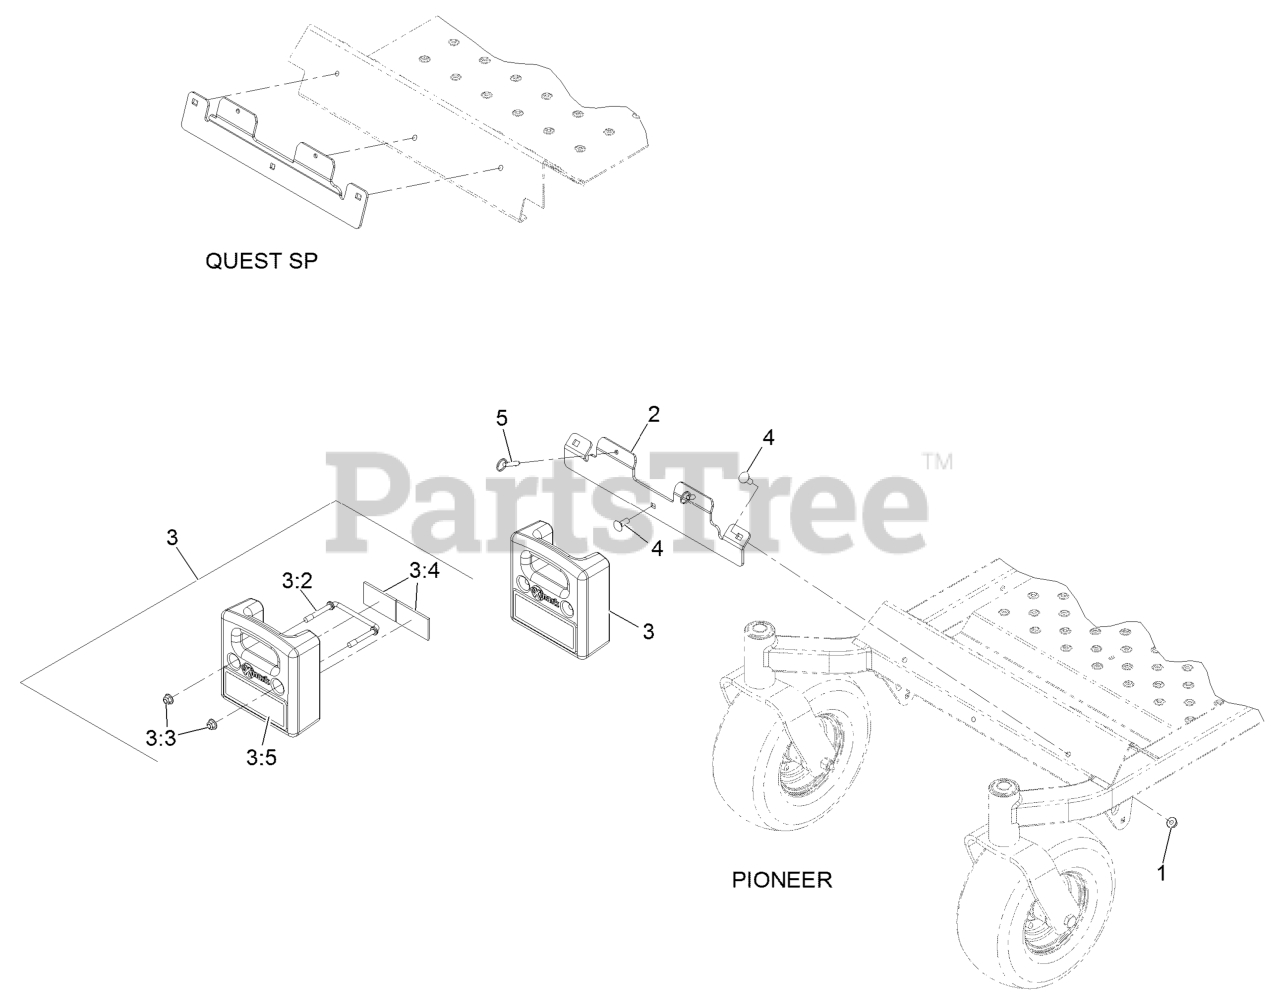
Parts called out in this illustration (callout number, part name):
1	NUT-HF, NI
2	BRACKET-WEIGHT MOUNT
3	WEIGHT ASM
3:2	WIREFORM-WEIGHT
3:3	NUT-HF, NI
3:4	CUSHION-RUBBER
3:5	DECAL-WARNING WEIGHT
4	BOLT-CARR
5	PIN-BALL, DETENT
